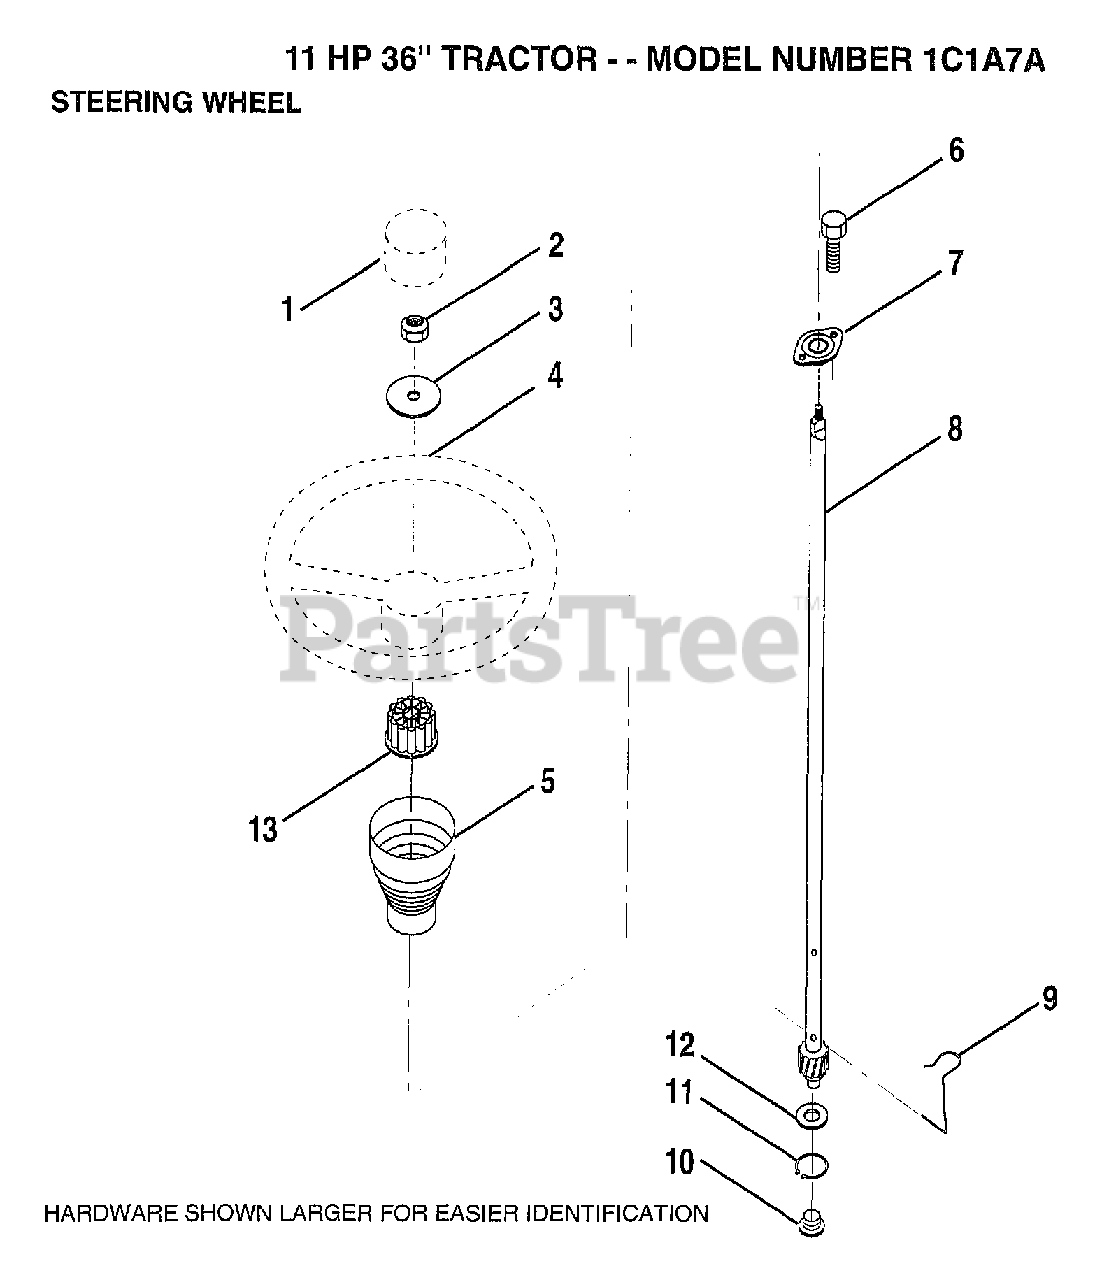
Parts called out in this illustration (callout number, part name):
1	ST WHL INSERT CAP
2	GRIPCO NUT
3	WASHER T
5	SLEEVE STEERING
9	STEERING CLIP
10	BUSHING STEER LWR
11	RING
12	WASHER LT
13	ADAPTER-WHEEL LT
